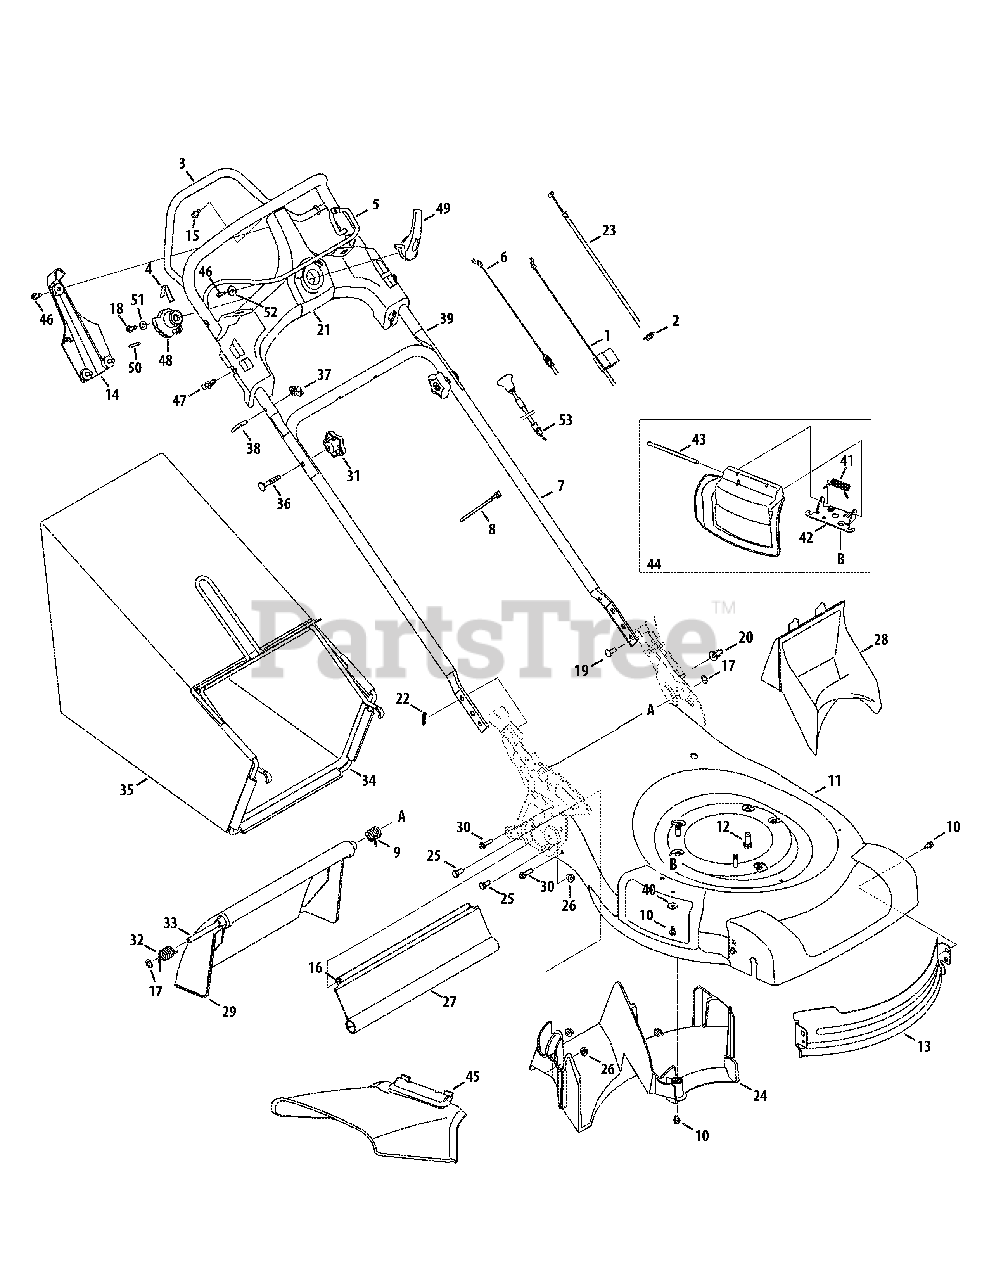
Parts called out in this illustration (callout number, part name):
1	Drive Cable
2	Rubber Grommet
3	Drive Control
4	Shift Spring
5	Blade Control
6	Control Cable
8	Cable Tie
9	Torsion Spring, LH
10	TT Screw, 1/4-20 x .500
12	TT Screw, 3/8-16 x 1.00
13	Front Deck Baffle
14	Variable Spd. Cont. Panel Cover
15	Screw, TT, 1/4-20 x .750
16	Screw, #10-16 x .500
17	Nut, Speed
18	Screw, 1/4-15 x .750
19	Carriage Bolt, 1/4-20
20	Wing Nut
21	Variable Speed Control Panel
22	Cotter Pin
23	Variable Speed Cable
24	Rear Baffle
25	Screw, 5/16-18 x .625
26	Flange Lock Nut, 5/16-18
27	Trail shield
28	Rear Mulch Plug
29	Rear Door
30	Screw, 1/4-15 x 1.00
31	Star Knob
32	Torsion Spring, RH
34	Grass Catcher Frame
35	Grass Catcher
36	Carriage Bolt, 5/16-18 x 2.00
39	Upper Handle
40	Bell Washer, .265 x .75 x .062
41	Torsion Spring
42	Chute Deflector Adapter
43	Hinge Pin
44	Mulch Plug Assembly
45	Side Discharge Chute
46	Screw, #12-16 x .75
47	Rivet, Plastic
48	4 Speed Actuator
49	Speed Selector Level
51	Washer, Flat, .344 x .688 x .065
52	Washer, Flat, .250 x .750 x .119
53	Choke Cable
